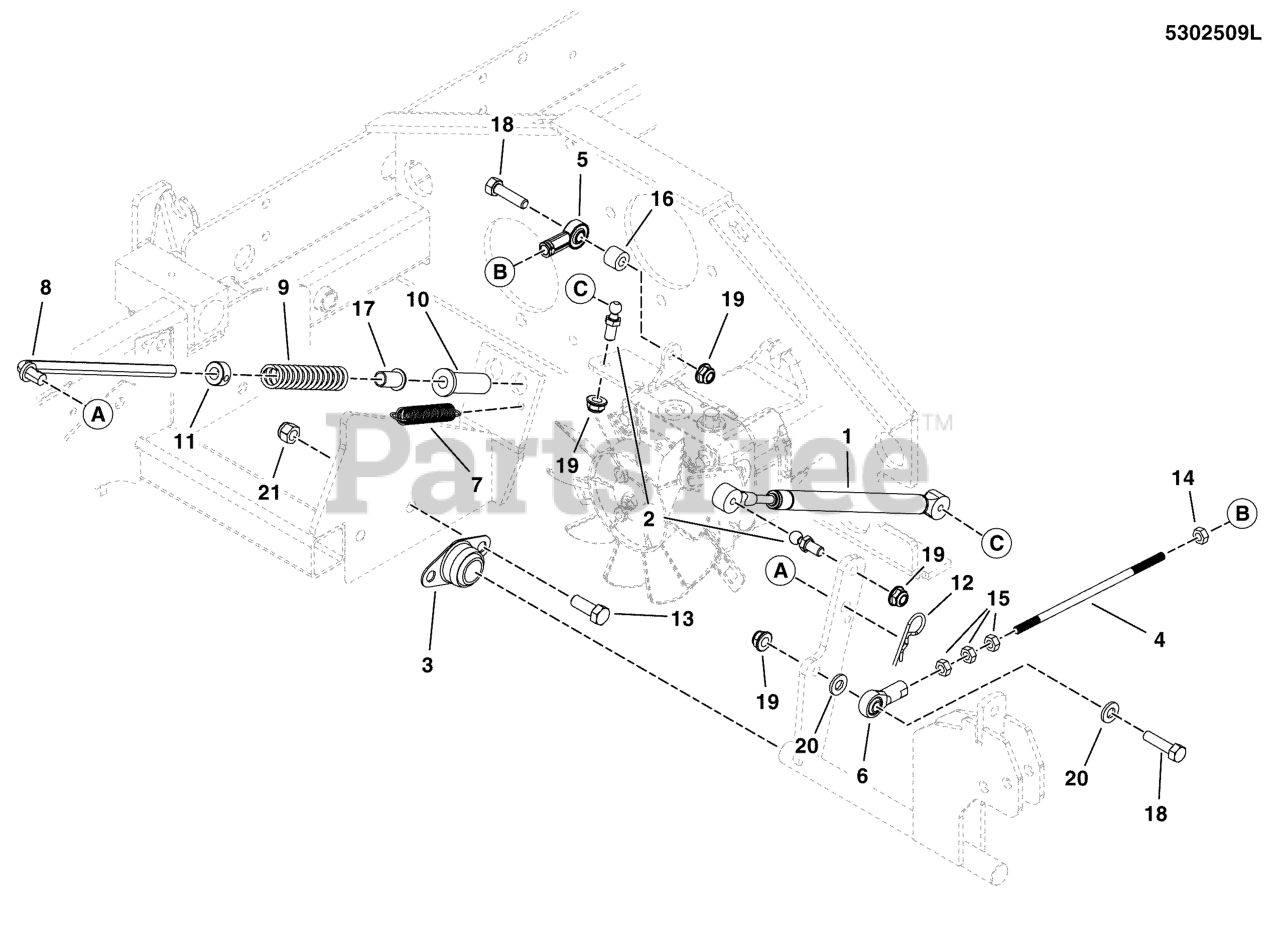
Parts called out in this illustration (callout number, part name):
1	DAMPENER, CONTROL,#(P6709/P3610)
2	10MM BALL STUD, 5/16-18 X 3/4 THDS
3	BEARING, BRONZE FLANGE, 3/4"
4	ROD, 5/16 X 8.38, LH-RH, CZ
5	BALL JOINT 5/16-24 LH FEMALE STAMPED STL
6	BALL JOINT 5/16-24 RH FEMALE STAMPED STL
7	SPRING, EXTENTION, .50 OD X 4.12 FL
8	ROD, NEUTRAL RETURN, CZ
9	SPRING, REVERSE RETURN
10	FLANGED BUSHING, 3/8IDX.63ODX.8125FL
11	COLLAR, 3/8" Set
12	PIN, HAIR, .0585 X 1-1/8, 1/4 EYE, YZ
13	BOLT, 3/8-16 X 1" GD5 CZ
14	NUT, 5/16-24 HEX, LH
15	NUT, Hex, 5/16-24
16	SPACER-0.328IDX0.499ODX0.625LG PM
17	BUSHING, FLANGE 3/8ID X 7/8 LONG
18	BOLT, 5/16-18 X 1-1/4" GD5 YZ
19	NUT, 5/16-18 HEX NYLOCK FLANGE NUT
20	WASHER, 5/16" SAE
21	NUT, 3/8 - 16 HEX NYLOCK FLANGE
